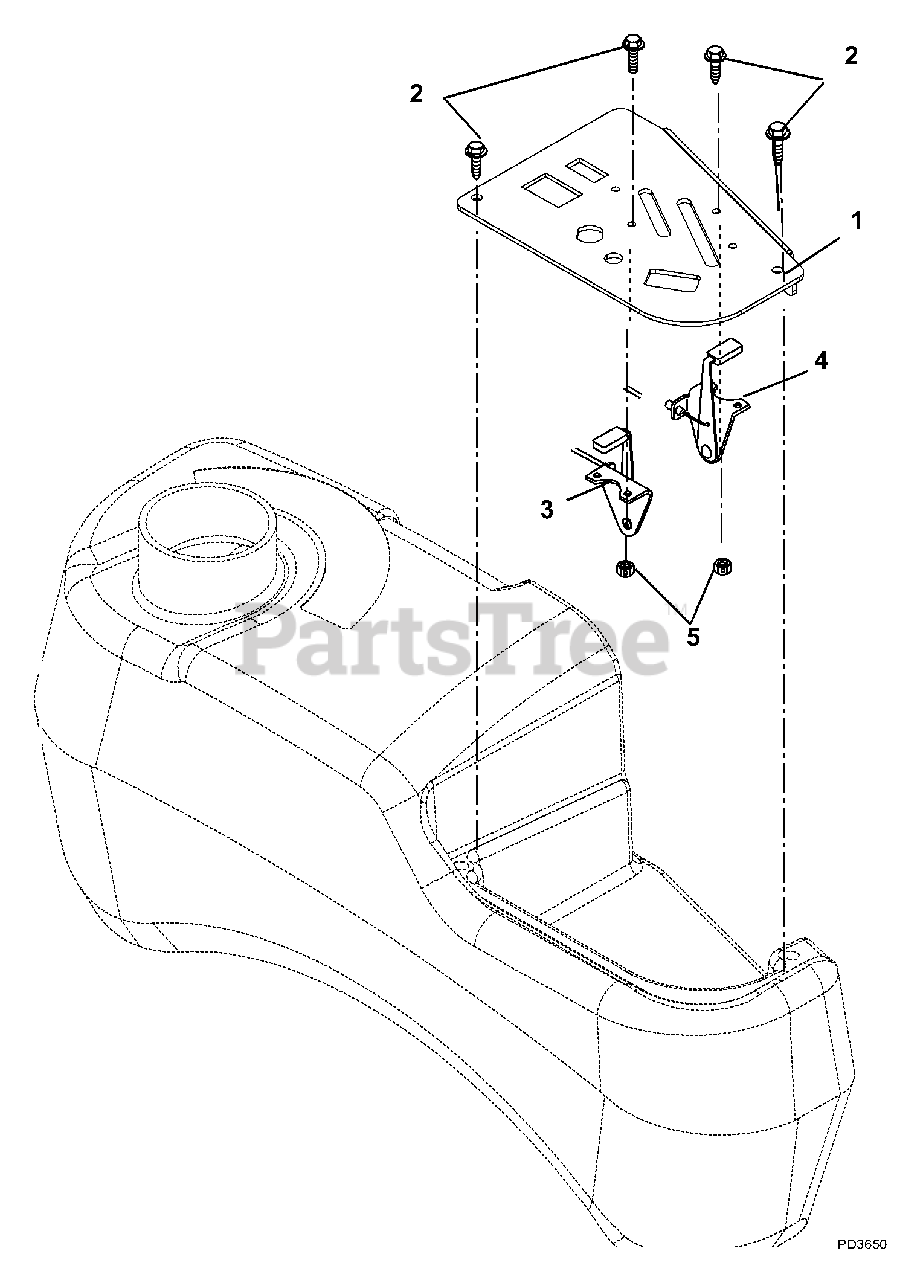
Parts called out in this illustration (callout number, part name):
1	Panel, Control
2	Screw, Machine 10-24 x .50 Hex Washer Head
3	Cable, Throttle
4	Cable, Kohler Choke
4	Cable, Choke, Kawasaki
5	Nut, Locking Nylon 10-24 With Insert
